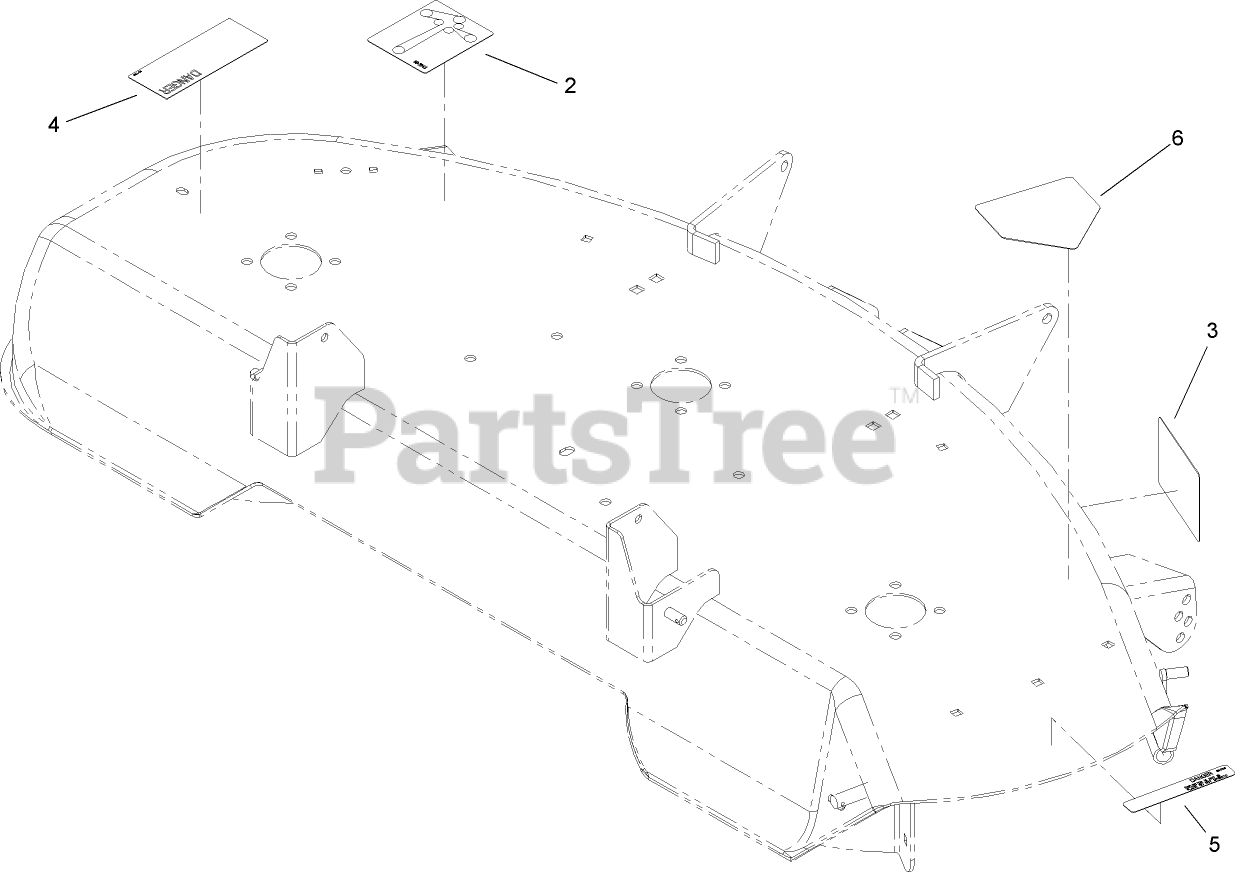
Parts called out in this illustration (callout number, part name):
2	DECAL-ROUTING, BELT
3	DECAL-WHEEL, GAGE
4	DECAL-DANGER
5	DECAL-CAUTION
6	DECAL-DANGER
